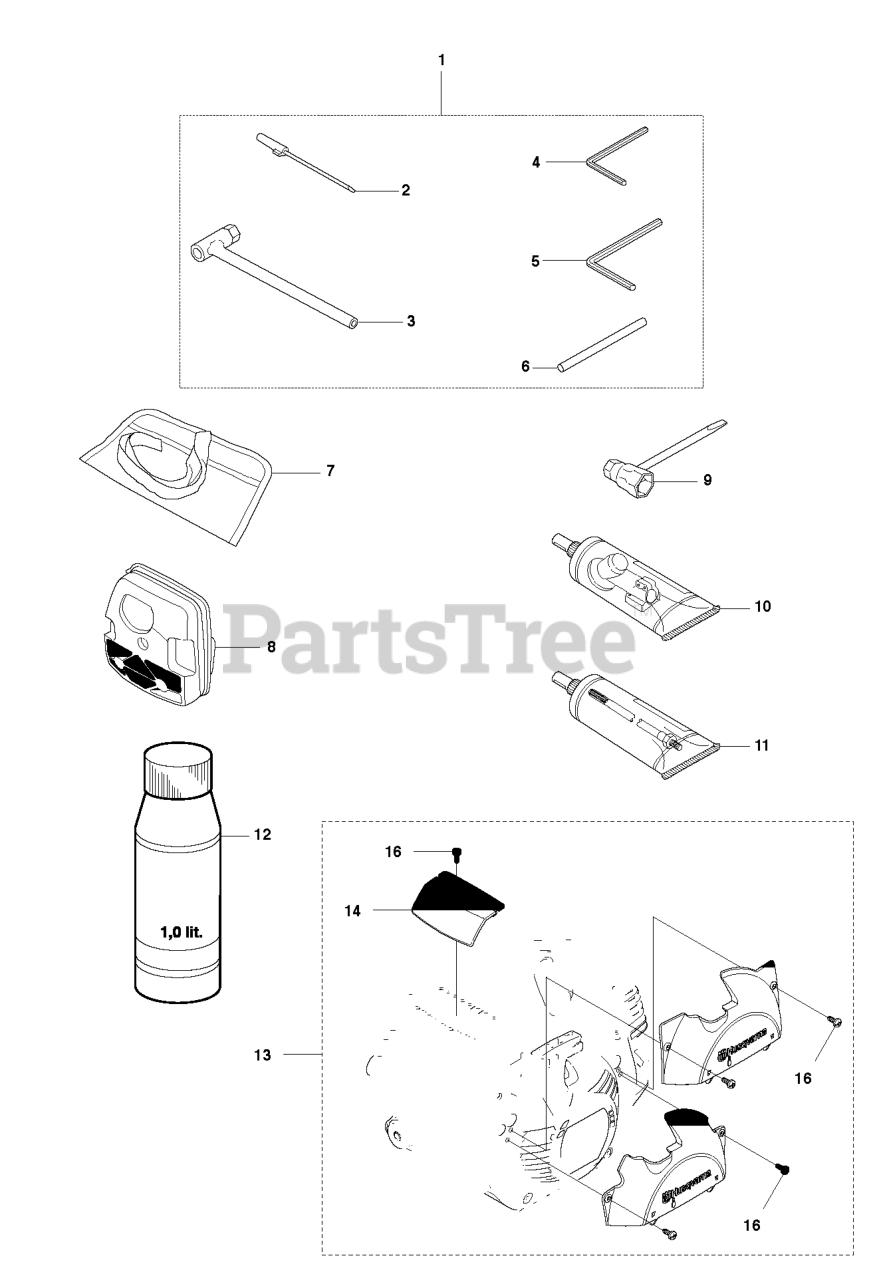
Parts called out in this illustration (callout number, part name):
1	TOOL KIT
2	SCREWDRIVER
4	L-KEY WRENCH
5	L-SPANNER
6	LOCKING PIN
8	FILTER
8	AIR FILTER
9	COMBI TOOL
10	BEVEL GEAR GREASE
11	DRIVE SHAFT GREASE (200 G)
12	Air Filter Oil 1l.
13	WINTER SET
